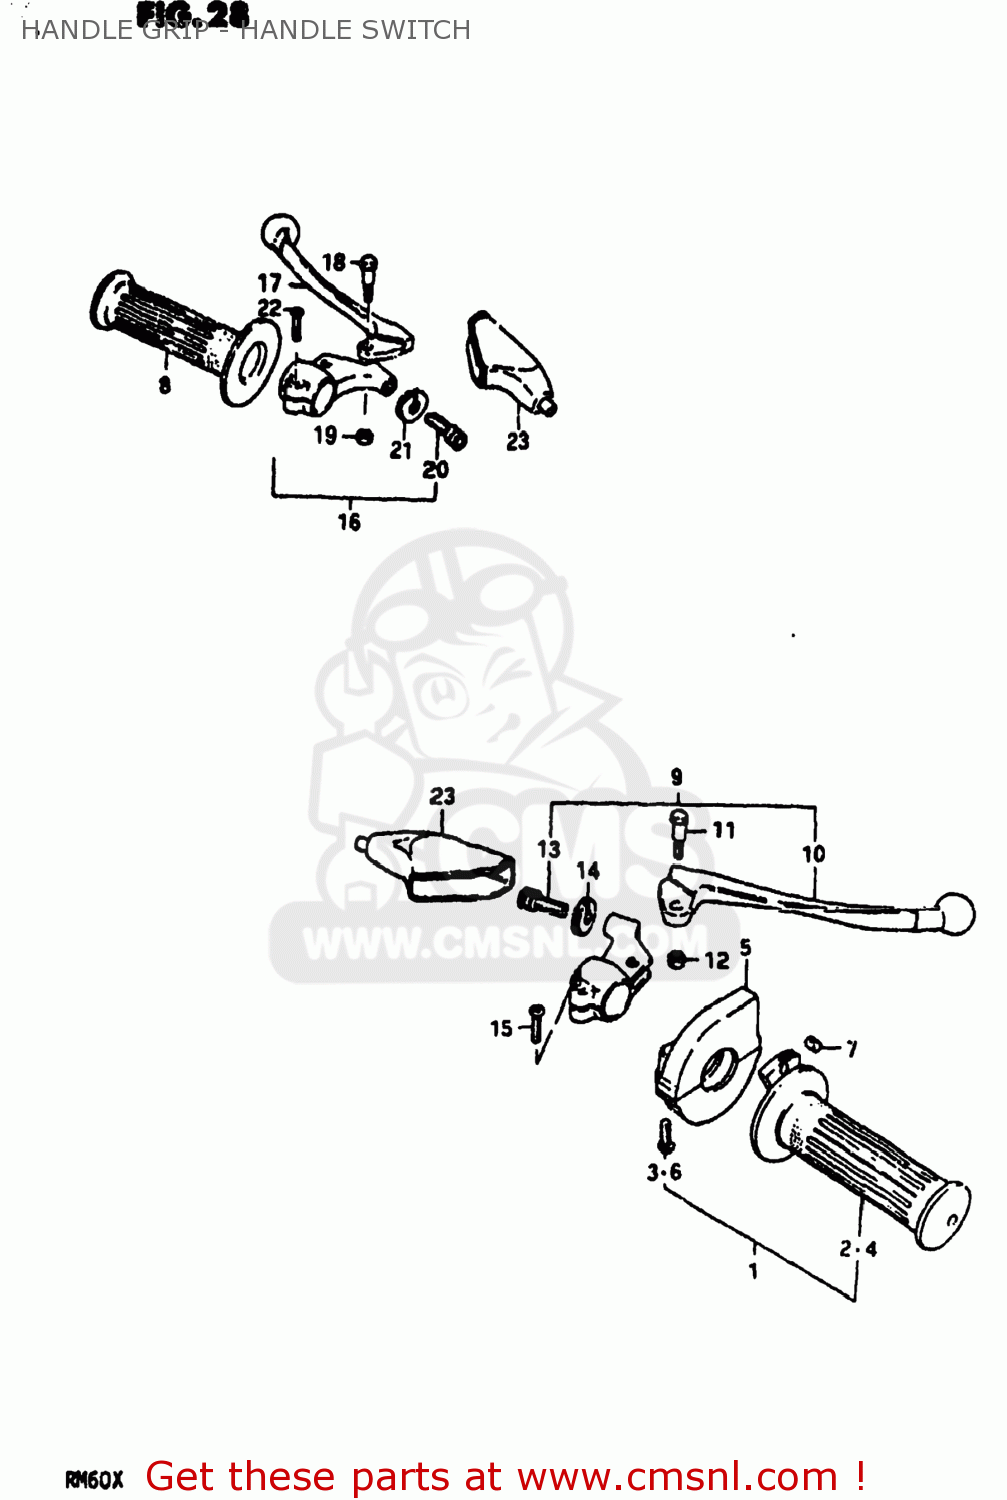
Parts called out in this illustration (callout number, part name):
1	CASE ASSEMBLY,THROTTLE
2	GRIP,THROTTLE
3	SCREW
4	GRIP,THROTTLE
5	CASE ASSY,THROTTLE
6	SCREW
7	PIECE,THROTTLE END
8	GRIP,L
9	LEVER ASSEMBLY,BRAKE
10	LEVER,BRAKE
11	BOLT,LEVER
12	NUT 6MM
13	ADJUSTER,CABLE
14	NUT,CABLE ADJUSTER
15	SCREW
16	LEVER ASSY,CLUTCH
17	LEVER,CLUTCH
18	BOLT,LEVER
19	NUT 6MM
20	ADJUSTER,CABLE
21	NUT,CABLE ADJUSTER
22	SCREW
23	COVER,CLUTCH LEVER
